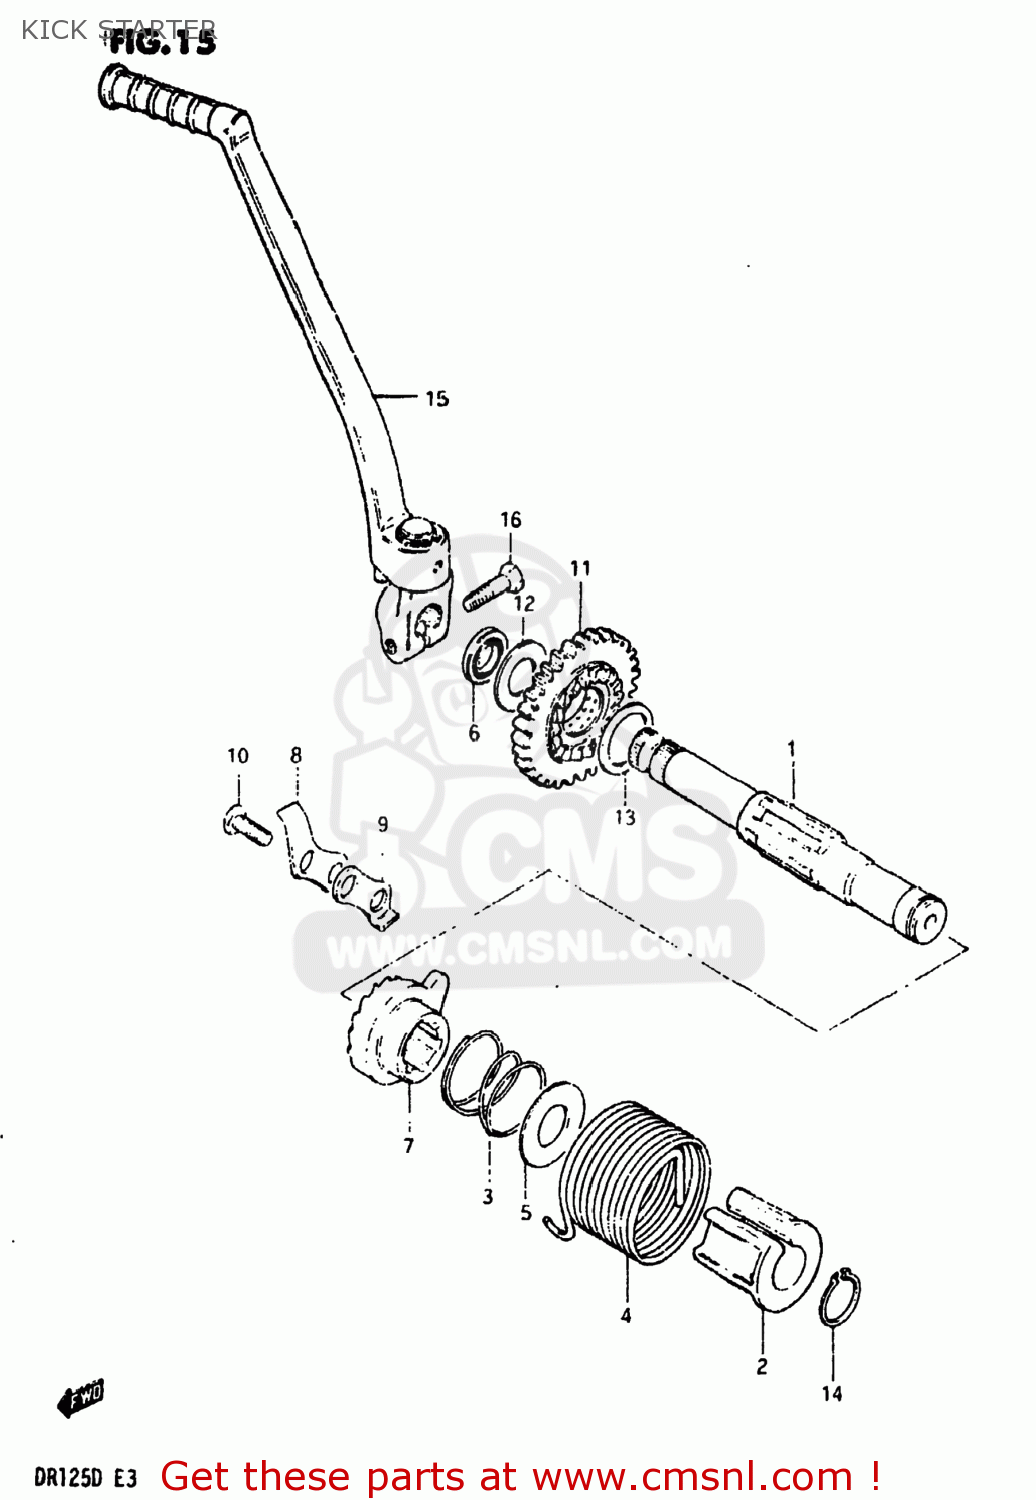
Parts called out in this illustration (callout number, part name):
1	SHAFT,KICK STARTER
2	GUIDE,KICK STARTER SFT SPRING
3	SPRING
4	SPRING
5	WASHER
6	SEAL,OIL(16X24X5)
7	STARTER,KICK
8	GUIDE,KICK STARTER
9	STOPPER,KICK STARTER
10	BOLT
11	GEAR,KICK STARTER DRIVE
12	WASHER(16X30X1)
13	WASHER
14	CIRCLIP
15	LEVER ASSEMBLY,KICK STARTER
16	BOLT 8X25
